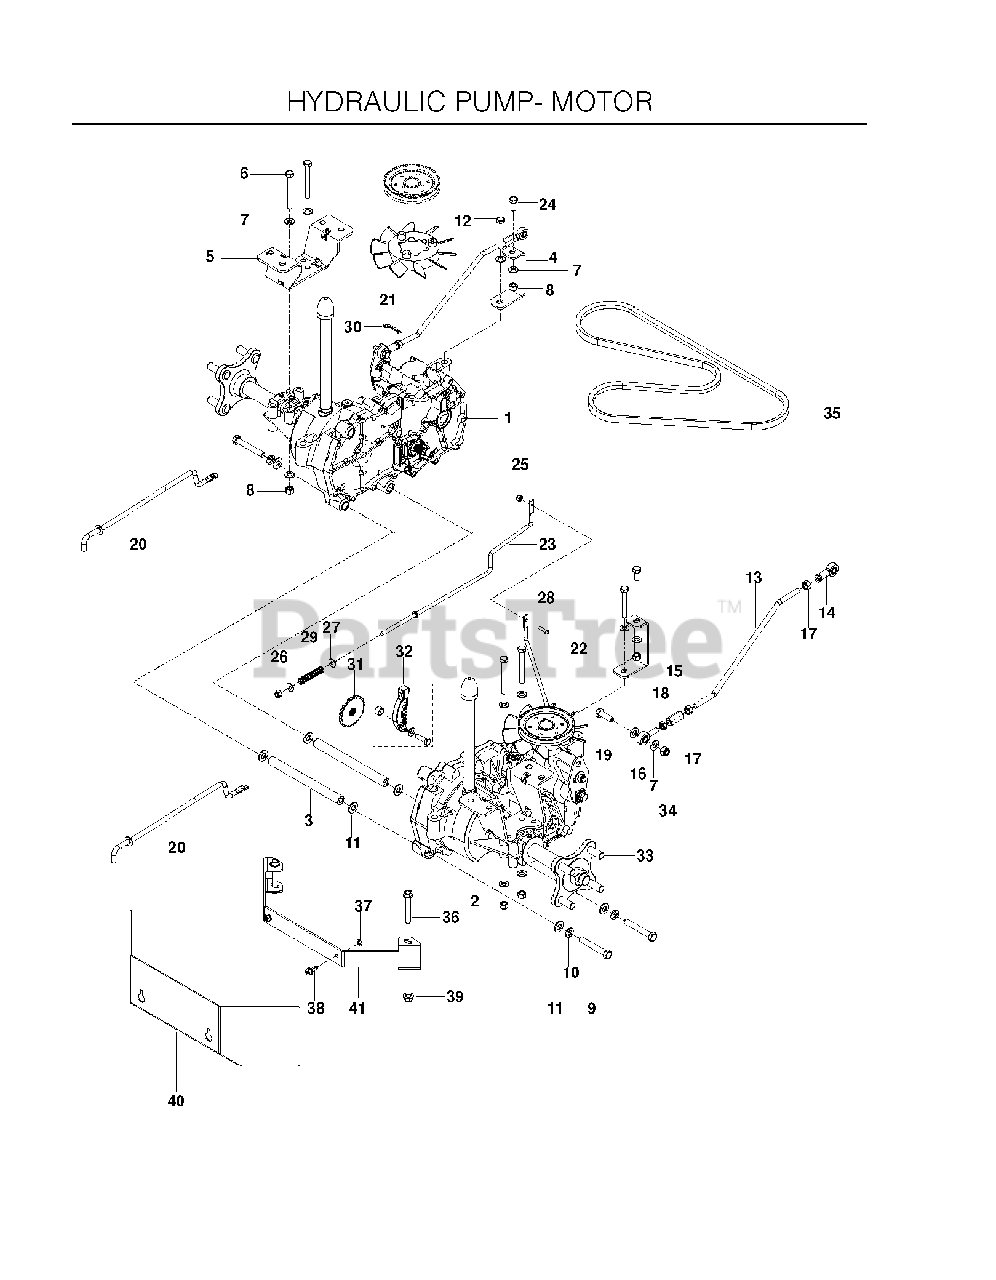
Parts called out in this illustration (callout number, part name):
1	HG_EZT, LT
2	HG_EZT, RT
3	SPACER TUBE, EZT
4	SUPPORT.FRONT.TRANS.BLACK.
5	EZT MOUNT, REAR, BLACK
6	HCS 5/16C X 2-3/4
7	FLAT WASHER 5/16 SAE
8	NUT 5/16 NYLOC
9	HCS 3/8C X 2 1/2
10	SLW 3/8 STD
11	WASHER 3/8 SAE FLAT
12	CAPSCREW
13	ROD, MOTION CONTROL
14	RH ROD END
15	ROD END COUPLER
16	ROD.END.LH
17	NUT 5/16F
18	NUT 5/16F LEFTHAND
19	HCS 5/16C X 1
20	LINKAGE, BYPASS, EZT
21	HG_HYDRO FAN
22	LINKAGE.BRAKE.LT
23	LINKAGE, BRAKE RT
24	HCS 5/16C X 3/4
25	NUT 10-24 NYLOC
26	NUT 1/4-20 NYLOC
27	WASHER 1/4 SAE
28	SCR #10-24 X 3/4
30	HAIRPIN #2
31	HG_DISC COG BRAKE
32	HG_KIT BRAKE ARM (EZT)
33	HUB KIT (H-G #70314)
34	5/16-18 THIN PROF NY
35	BELT, HYDRO PUMP
36	HHFS 5/16-18 X 2.25 GD 5
37	PALNUT 1/4
38	SCREW- 1/4-20 X 5/8
39	5/16-18 NYLOC FLANGE NUT
41	BRACKET, GUARD
